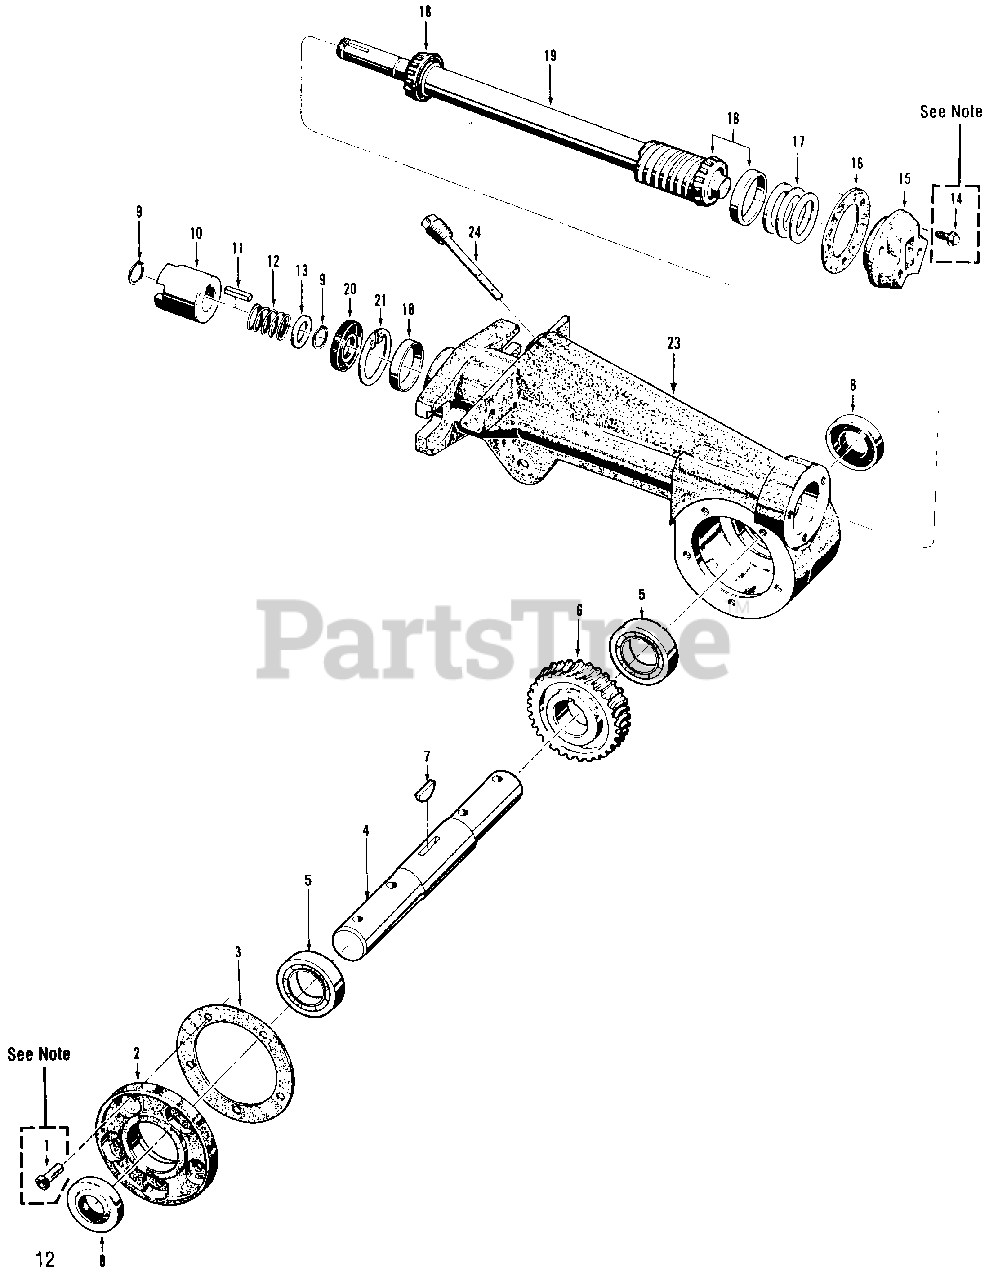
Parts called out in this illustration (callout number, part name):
1	Screw Kit
2	Cover-tiller housing
3	Gasket-tiller housing cover, .010". As thick
3	Gasket-same as above, .030" As thick
4	Shaft-tiller tine
5	Ball Bearing
6	Worm Gear-bronze, tiller tine shaft
7	Key-tiller tine shaft, woodruff key.
8	Seal-oil, tiller tine shaft
9	Retaining Ring-external
10	Dog Clutch-tiller drive shaft
11	Key-3/16" x 1"
12	Spring-dog clutch
13	Shim-dog clutch, 1/16"(.62") thick
14	Screw Kit
15	Cap-rear bearing
16	Gasket-rear bearing cap
17	Shim-front bearing cap, .010" As thick
17	Shim-same as above, .030" As thick
17	Shim-same as above, .005" As thick
17	Shim-same as above, .062" As thick
18	Bearing & Cup-sold as set only
19	Shaft-main tiller drive
20	Seal-oil, drive shaft, front
21	Retaining Ring-internal
23	Housing-tiller attachment
24	Dipstick-oil, tiller attachment
